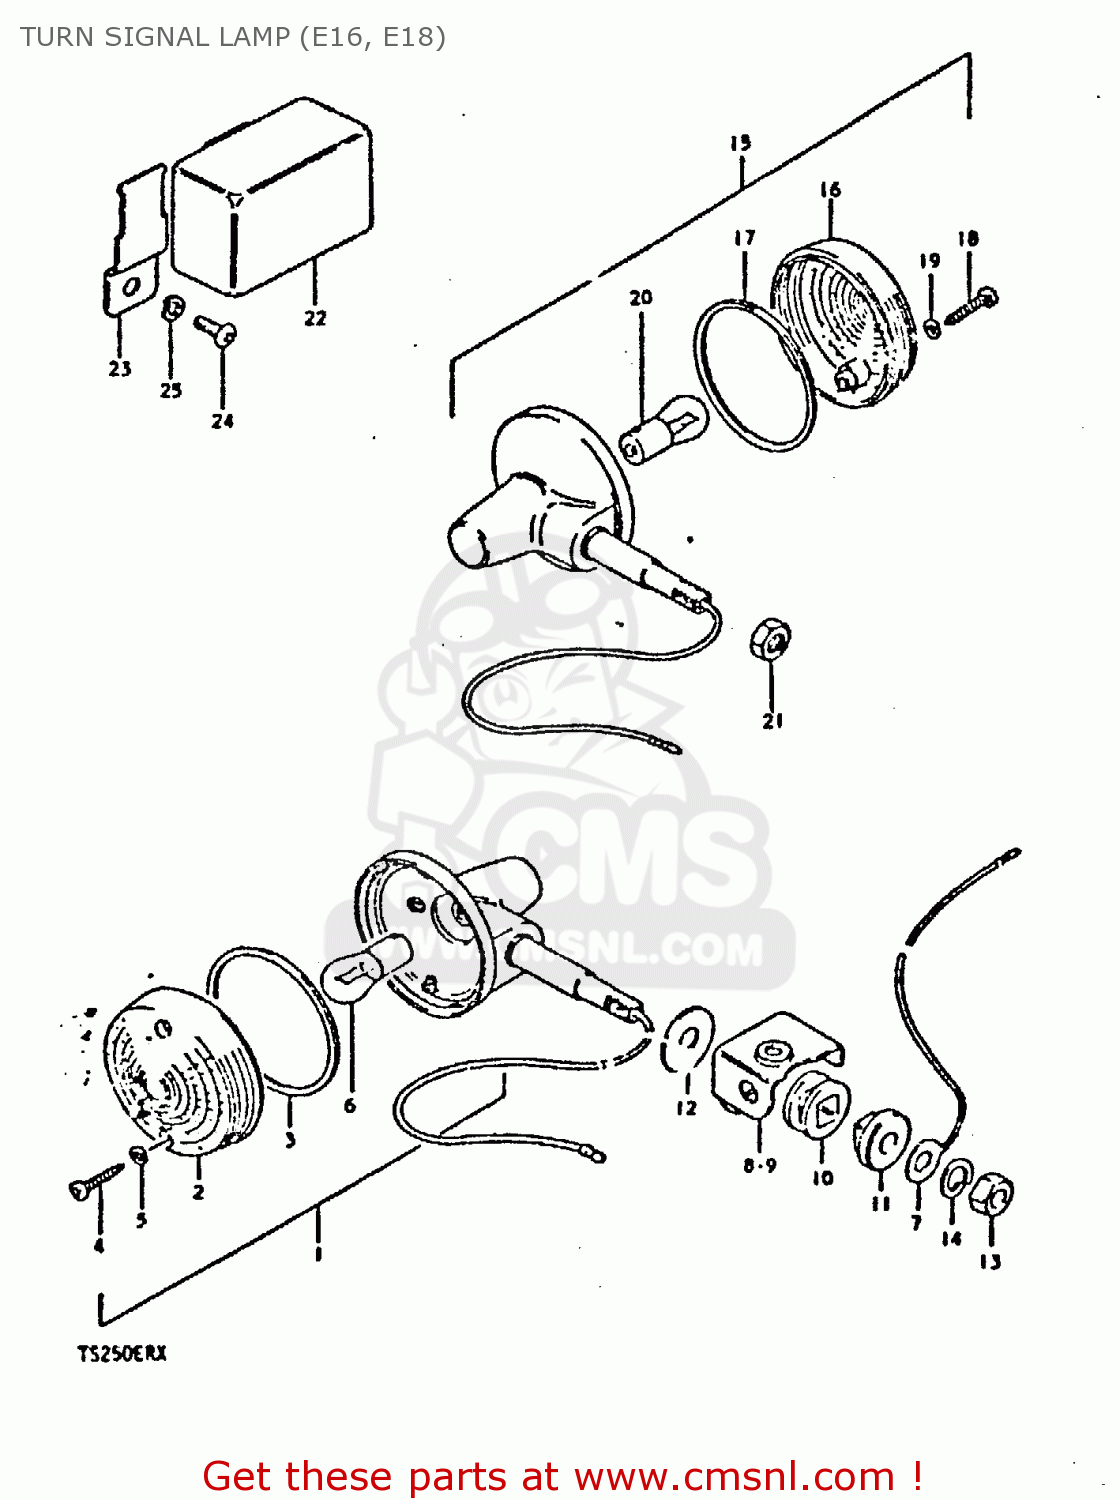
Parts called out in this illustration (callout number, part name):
1	LAMP, FRONT TURN SIGANL
2	LENS
3	GASKET (NAS)
4	SCREW
5	GASKET (NAS)
6	BULB (6V,21W)
7	LEAD WIRE,EARTH
8	BRACKET,TURNSIGNAL LAMP,R
9	BRACKET,TURNSIGNAL LAMP,L
10	CUSHION
11	SPACER,RR TURNSIGNAL LAMP
12	WASHER (10.5X30X2.3)
13	NUT
14	LOCK WASHER
15	LAMP, REAR TURN SIGNAL
16	LENS
17	GASKET (NAS)
18	SCREW
19	GASKET (NAS)
20	BULB (6V,21W)
21	NUT
22	RELAY, TURN SIGNAL
23	BRACKET,TURN SIGNAL RELAY
24	SCREW
25	LOCK WASHER
